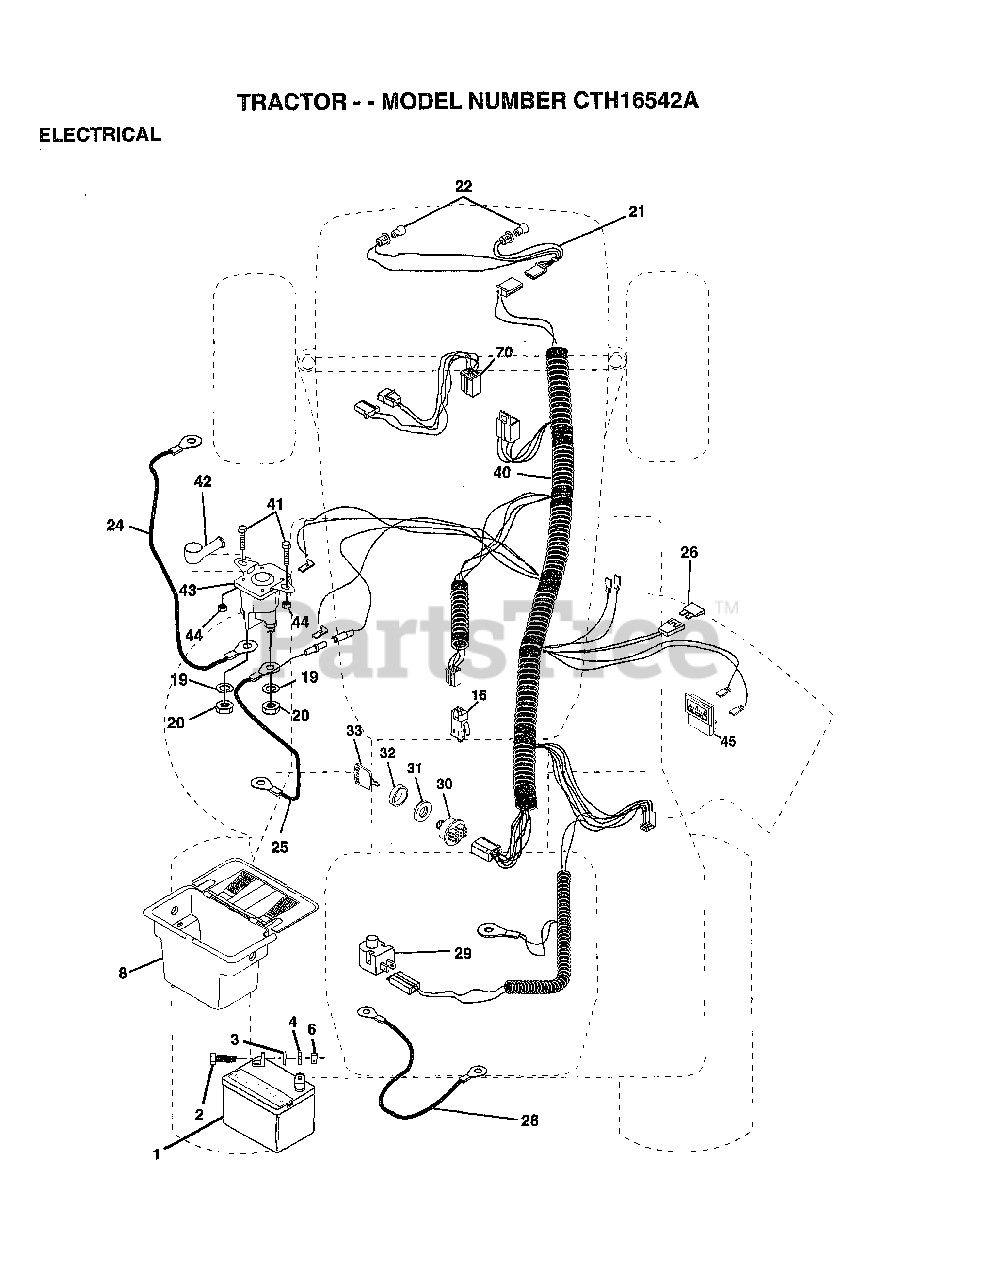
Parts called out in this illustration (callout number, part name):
3	WASHER
4	LOCKWASHER
8	"CASE,BATTERY.MECH"
16	SWITCH INTERLOCK
20	NUT
21	"HARNESS,LIGHT SOC"
22	HEADLAMP BULB
24	CABLE.BTRY.6GA.38
25	CABLE.BTRY.6GA.RD
26	FUSE HYT
28	CABLE T
29	SWITCH SEAT
30	SWITCH IGN 4POS
31	NUT IGNITION
32	COVER KEY SWITCH
33	KEY
40	HARNESS IGNITION
41	BOLT HXHD FIN
44	NUT HXKEP 1/4X20
70	HARNESS.ENG.DUAL
